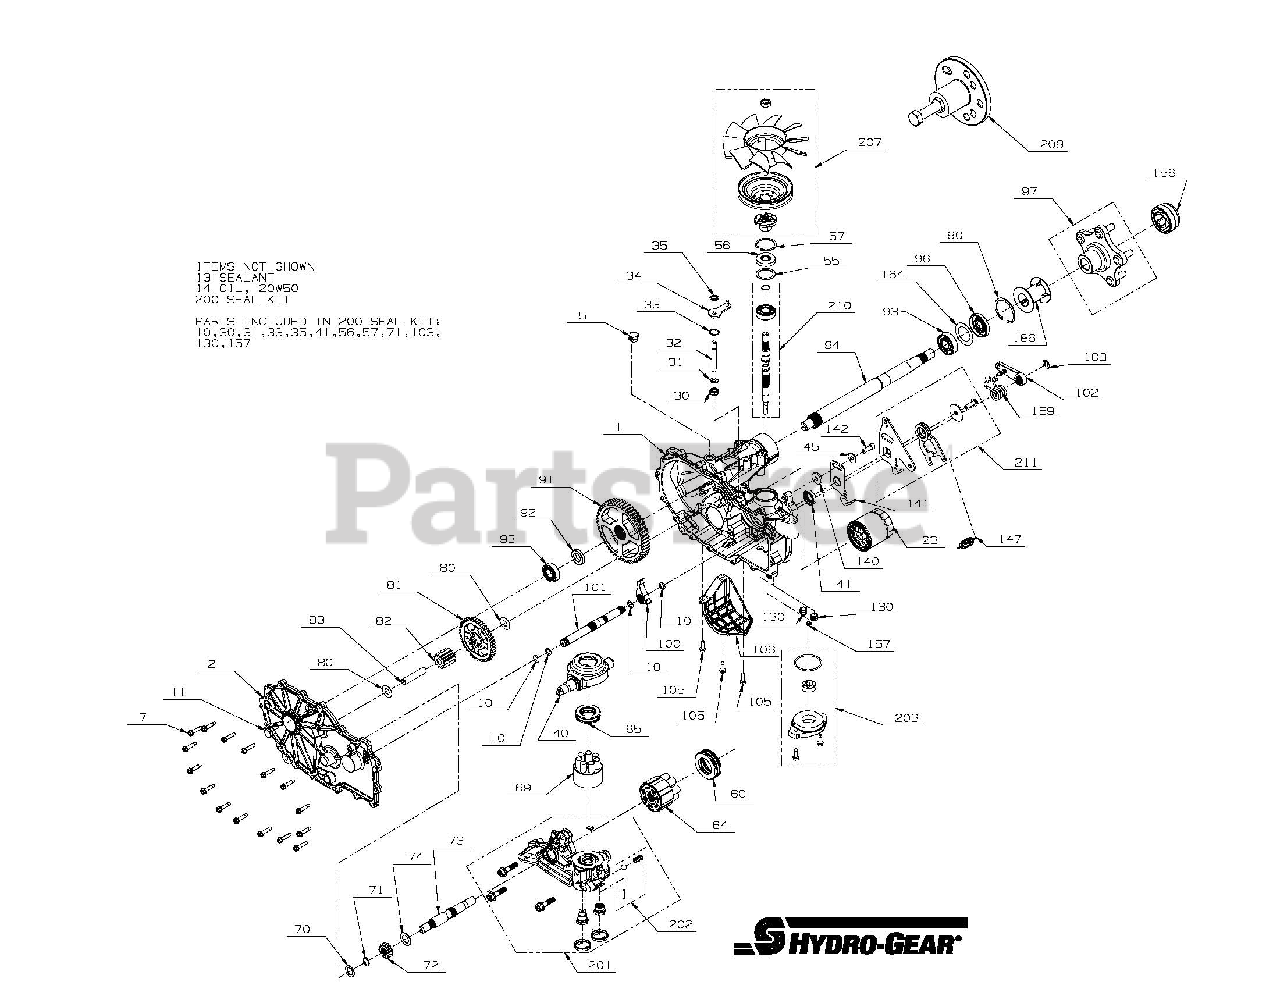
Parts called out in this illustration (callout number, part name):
7	SCREW, HEX WASHER
13	TUBE, SEALANT
23	FILTER, SPIN-ON 2.6 X 3.0
30	SEAL, LIP .375 X .75 X .25
31	RING, RETAINING EXTERNAL .375
33	RING, RETAINING .750, INTERNAL
34	ARM, BYPASS
35	RING, RETAINING .375 EXTERNAL
40	SWASHPLATE, TRUNNION
41	SEAL, LIP 18 X 32 X 7
45	WASHER FLAT .34 X .88 X .06
55	WASHER, FLAT 1.23 X 1.57 X .04
56	SEAL, LIP 17 x 40 x 7
57	RING RETAINING INTERNAL
60	BEARING, THRUST 35 x 62 x 18
64	KIT, 16cc CYLINDER BLOCK ASSEMBLY
65	BEARING, THRUST 30 x 52 x 13
69	KIT, BLOCK 7 PISTON
70	WASHER, .63 X 1.00 X .05 FLAT
71	RETAINING RING, MOTOR SHAFT
74	WASHER, .71 X 1.16 X .04 FLAT
80	WASHER, .51 X 1.00 X .03 FLAT
90	RING, RETAINING 2.25 INIERNAL
96	SEAL, LIP, TC4, 1.0 X 2.06 X .38
97	KIT, HUB - 5 BOLT
102	KIT, LEFT HAND BRAKE ARM
105	SCREW, HEX WASHER 1/4-20 X .75
106	GUARD, FILTER, LH
140	SPACER 0.320 ID X 1.005 OD X 0.1495 THK
141	ARM, RETURN LEFT
142	SHCS 5/16-24 x 7/8
147	SPRING, EXTENSION
200	KIT, SEAL, ZT-2800
203	KIT, CHARGE
207	KIT, FAN/PULLEY
209	KIT, HUB PULLER
210	KIT, INPUT SHAFT
211	KIT, RTN CCW
